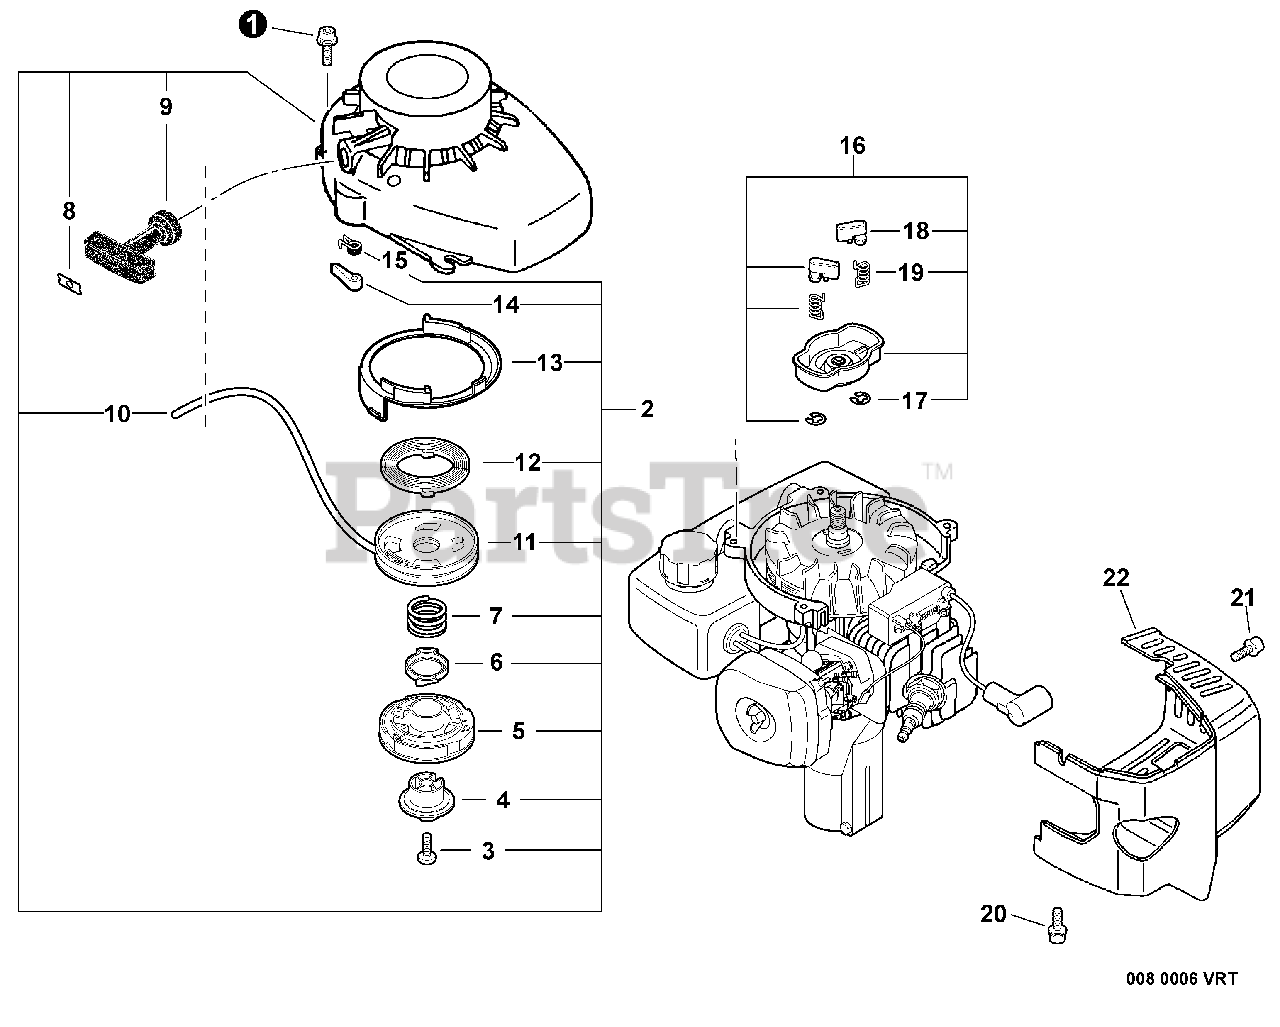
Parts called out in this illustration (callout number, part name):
1	BOLT 4×16
2	STARTER ASSY - GRAY
4	PLATE, CAM
5	SPRING ASSY
6	PAWL, STARTER
7	SPRING, RETURN
8	RETAINER, ROPE
9	GRIP, STARTER
10	ROPE, STARTER
11	PULLEY, STARTER
12	SPRING, RECOIL
13	CASE, STARTER
14	PAWL, STARTER
16	PAWL ASSY, STARTER
17	E-RING 4
18	PAWL, STARTER
19	SPRING, RETURN
20	BOLT 4×8
21	SCREW 4×18
30	COVER, ENGINE
